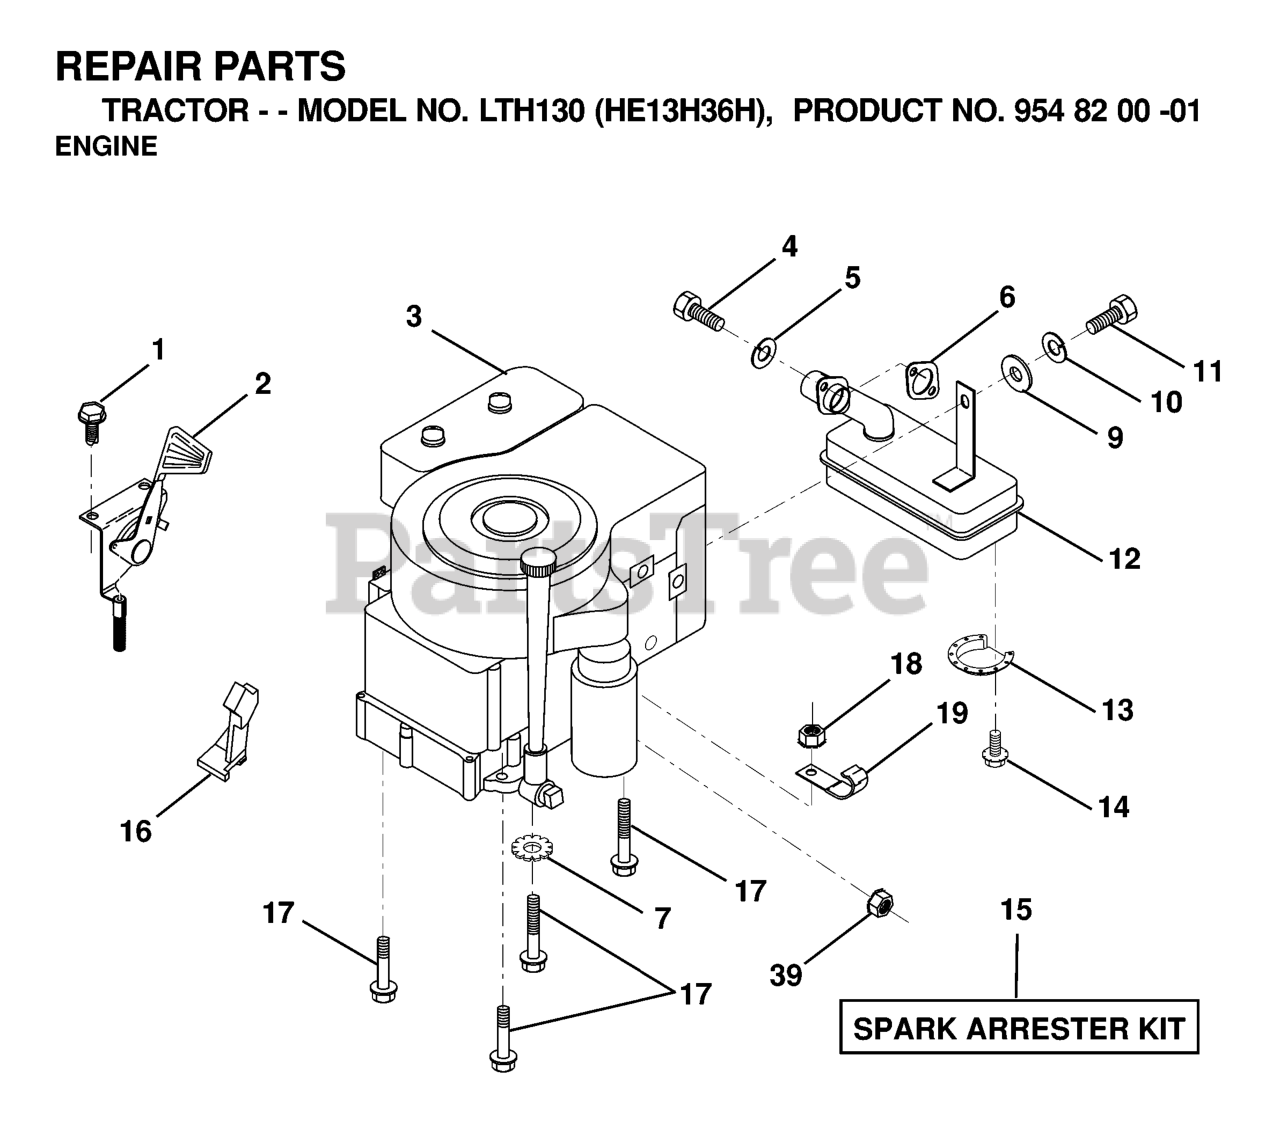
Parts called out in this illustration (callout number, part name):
2	SPRING,BRAKE RETURN
3	PULLEY TRANS
4	RETAINING RING LT
5	STRAP TORQUE
6	SCREW 5/16"
8	ROD SHIFT FENDER ADJUST STLT
10	PIN COTTER
11	WASH-SHFT PLT LT
13	BOLT 1/4-28X3/4
14	LOCKWASHER
16	NUT.71038.31-18.HEX.NYLOCK
19	NUT
21	KNOB.DUCKHEAD.1/2
24	NUT
25	SPRING ROD LT
26	WASHER
27	COTTER PIN
28	ROD BRAKE PARK LT
29	PLUNGER CAP
30	BRACKET TRANSAXLE
31	KEEPER BELT LH
32	BOLT
34	SHAFT, FOOT PEDAL
35	BEARING.NYLON
37	DRIVE PIN
38	FLAT IDLER PULLEY
41	KEEPER.BELT.IDLER.FLAT
42	WASHER
47	IDLER PULLEY
48	BELLCRANK, CLUTCH
49	RETAIN BELT
50	BOLT
52	LOCKNUT
53	LINK, CLUTCH LT
55	SPRING, RETURN LT
59	Keeper, Center Span
61	SCREW 3/8-16X3/4
62	COVER, PEDAL (1 2)
63	PULLEY.ENG.CL.MECH.SLVR.LT/YT
64	BOLT
65	LOCKWASHER
66	KEEPER BELT ENGINE
70	KEEPER BELT ENG
72	WASHER
74	SPACER AXLE
77	SQUARE KEY
79	KEY STD (1373) DANA
81	SHAFT ASM CROSS TAPERED
82	SHIFT SPRING
83	WASHER
84	LINK.TRNSAXLE
85	NUT LOCK CENTER 1/4 -28 FNTHD
90	NUT.PUSH.3/16
96	RETAINER M
113	STRAP TORQUE LH LT
116	BOLT
150	BUSHING.BELLCRANK.GRD.DR
151	WASHER 12/32X2X10GA
156	WASHER.SRRTD.5/16
158	BRACKET
159	HUB
161	BOLT
162	NUT.CROWNLOCK.1/4
164	Washer 5/8 x .281 x 10 Ga.
165	RP BRACKET
168	BOLT.SHOULDER.5/16-18X
169	PLATE.FASTENING.CROSS.SHAFT
197	NYLINER SNAP 5/8" ID
198	WASHER.NYL.7/8IDX.105"HYD CR
202	BOLT.3/8-16X1.50
